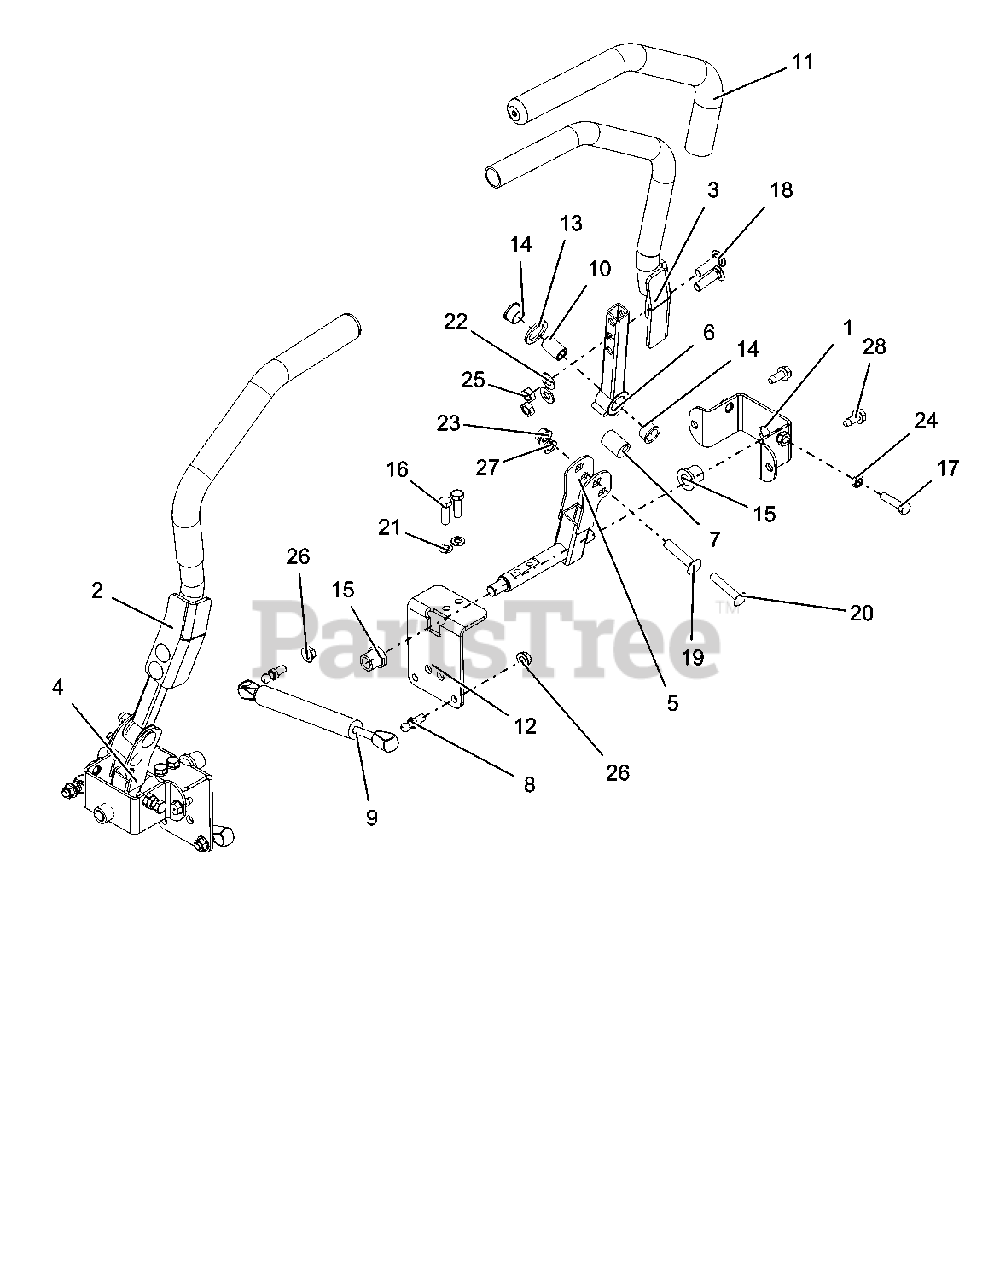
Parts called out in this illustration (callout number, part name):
1	BRKT, STEERING SUPPORT
2	WLDMT, STEERING HANDLE RH
3	WLDMT, STEERING HANDLE LH
4	WLDMT,STEERING ARM LOWER RIGHT
5	WLDMT,STEERING ARM LOWER LEFT
6	WLDMT, UPPER CONTROL ARM
7	BSHG,ECCEN .328X.750X1.01 PM
8	STUD- BALL
9	DAMPER, STABILUS
10	SPACER, .375X.625X.970 (PM)
11	GRIP, HANDLEBAR 15" FOAM
12	BRKT, STEERING
13	WASHER, FRICTION .875X1.25X.10
14	BSHG-FLG, .625X.75X.450X.875
15	BSHG-FLG .515X.750X.745X1.00NY
16	BLT-HEX .31-18X1.00 GR8 YWZC
17	@BLT-HEX .31-18X1.25 GR5 YWZC
18	BLT,RHSSN .38-16X1.25 G5 BFP
19	BLT,RHSSN .38-16X1.75 G5 BFP
20	BLT,RHSSN .31-18X1.75 G5 BFP
21	@WSHR-LK .31X.078 REG YWZC
22	@WSHR-FL-STL.406X.812X.065 YWZ
23	NUT-LK-CTR-FLG .38-16 YWZC
24	NUT- JAM .312-18 YWZC
25	@NUT-LK-CTR-JAM .375-16 YWZC
26	@NUT-LK-TOP-FLG .31-18 YWZC
27	@NUT-LK-NYL-FLG .31-18 YWZC
28	@SCR-TAP .31-18X.75 HWH TR YWZ
